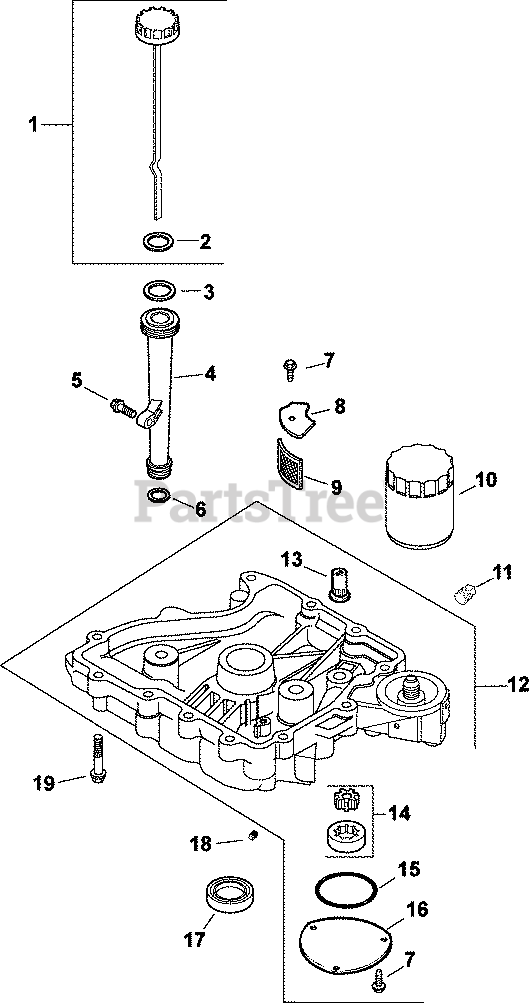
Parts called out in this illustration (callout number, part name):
1	DIPSTICK/CAP ASSY (BLACK)
2	O-RING, DIPSTICK
3	O-RING, UPPER OIL FILL TUBE
4	TUBE, OIL FILL USE 25 123 07-S
5	SCREW, FLG THD FRM M5X.8X20-(#25086399S)
6	O-RING, LOWER OIL FILL TUBE
7	SCREW,FLG THD FRM M5X0.8X16-(#25086398S)
9	SCREEN, OIL-USE 24 162 26-S
10	OIL FILTER
11	PLUG, SQ HD PIPE 3/8"
12	PAN, OIL
13	VALVE, OIL PRESSURE RELIEF
14	PUMP ASSEMBLY, OIL - DISCONTINUED
15	O-RING (2.5" DIA)
16	COVER, OIL PUMP
17	SEAL, OIL
18	PLUG, PIPE 1/8 NPTF-SQ.HD.
19	SCREW, FLG M8X1.25X45
